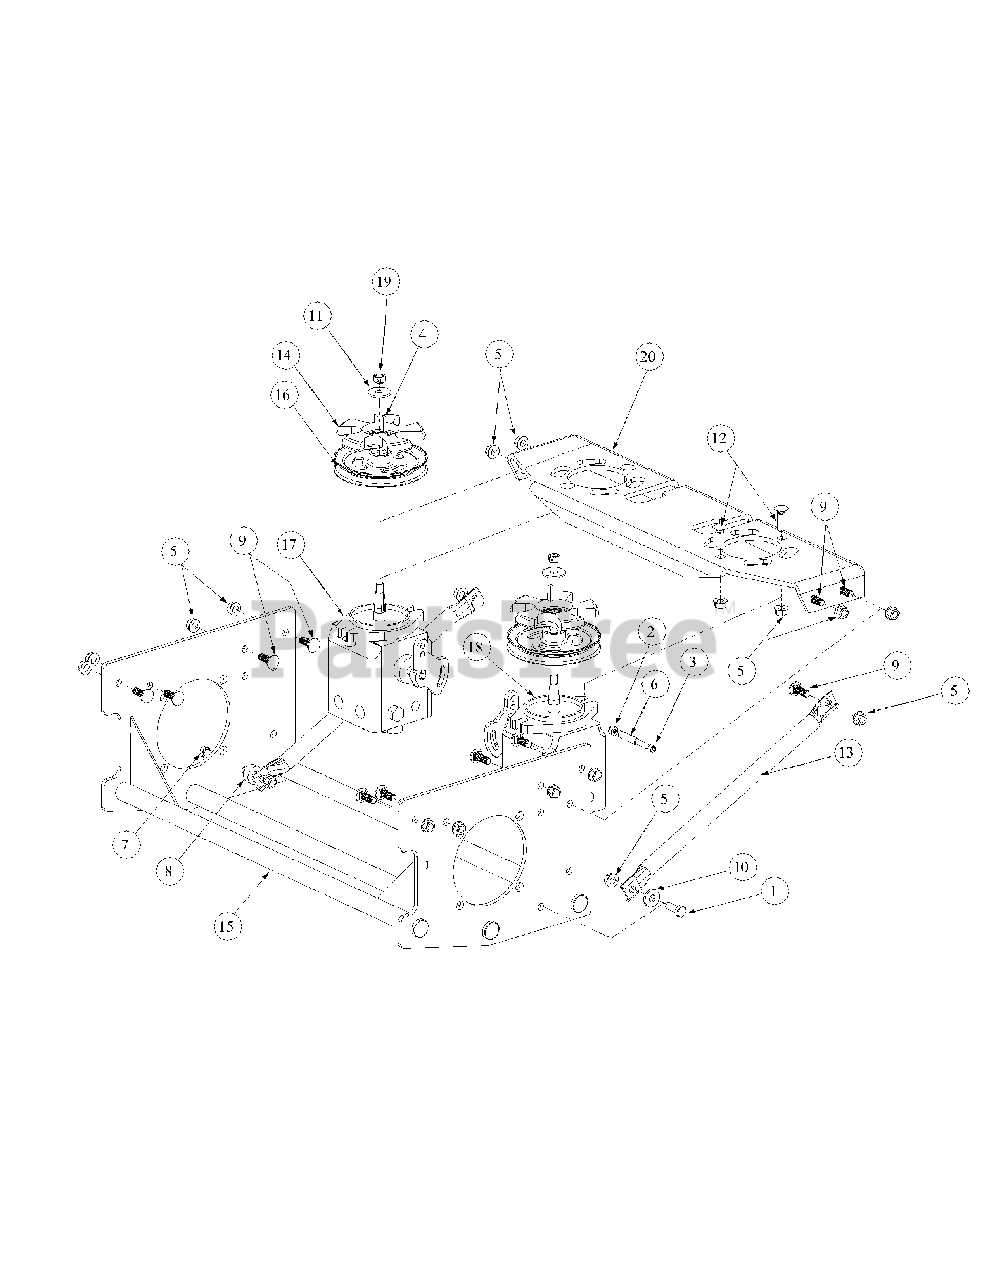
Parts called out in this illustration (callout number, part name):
1	Hex Cap Screw, 3/8-16 x 1
2	Lock Nut, Nylon Insert, 1/4-20
3	Socket Head Cap Screw, 1/4-20 x 2-1/2
4	Key, 3/16" x 7/8"
5	Flange Lock Hex Nut, 3/8-16
6	Pump Spacer
7	Hex Cap Screw, 2/8 -16 x 1.25
8	Spacer, .406 ID x 1.00 OD x .38
9	Carriage Bolt, 3/8-16 x 1
10	Flat Washer, .406 ID x 1.0 OD x .105
11	Flat Washer, .411 x 1.25 x .100
12	Carriage Screw, 3/8-16 x 1.25
14	Hydro Pulley Fan
15	Hydro Motor Frame Assembly
16	Hydro Pulley Pump
17	Hydro Pump, LH
18	Hydro Pump, RH
19	Hex Nut, 3/8-24
20	Hydro Pump Mounting Weldment
